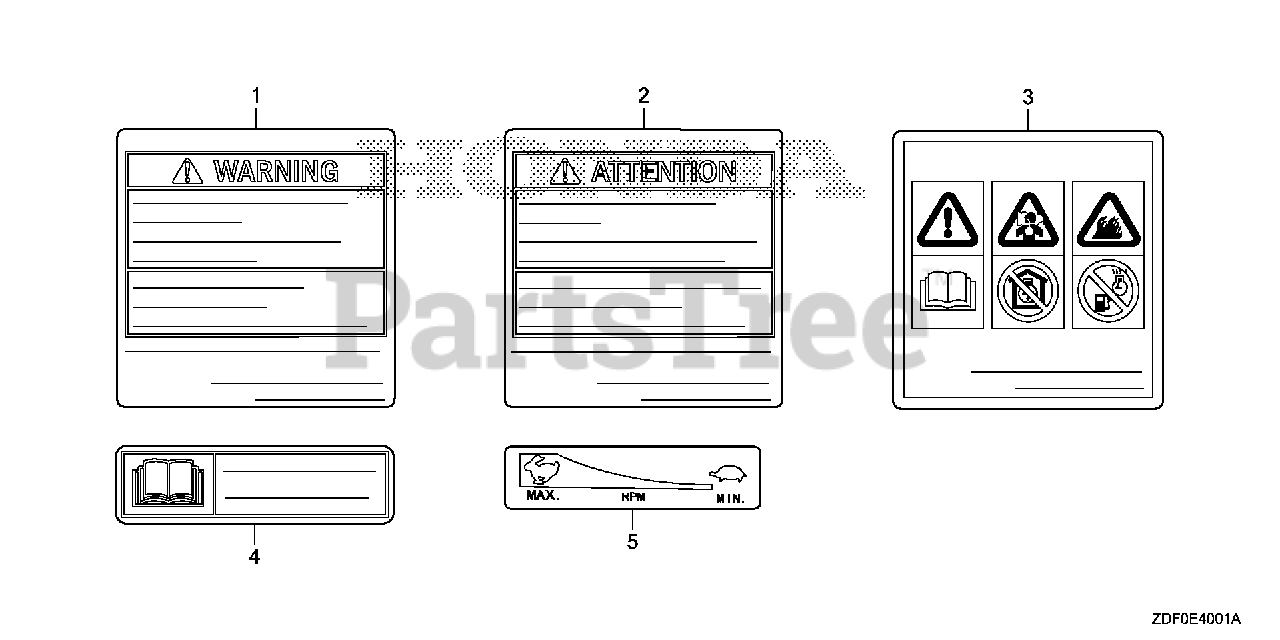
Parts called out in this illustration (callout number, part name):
1	MARK, OPERATOR CAUTION (ENGLISH)
2	MARK, OPERATOR CAUTION (FRENCH)
5	MARK, THROTTLE INDICATION
